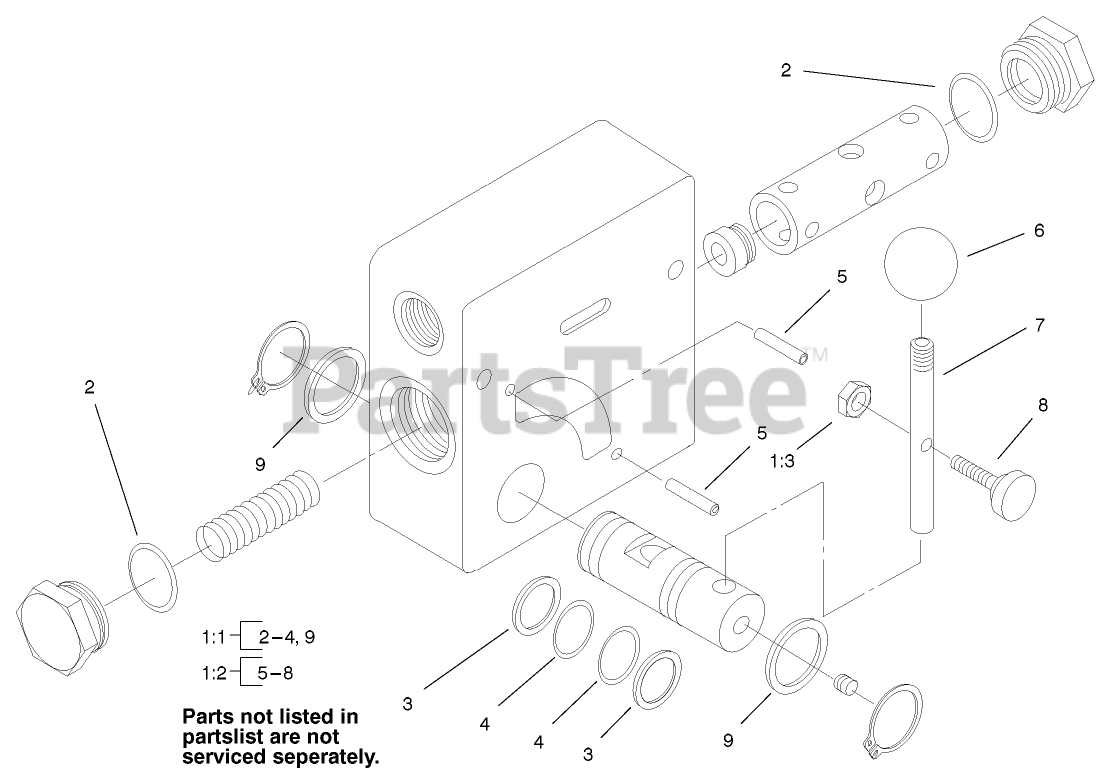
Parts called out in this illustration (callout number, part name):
1	VALVE-FLOW, HYDRAULIC
1:1	SEAL KIT
1:2	HANDLE HARDWARE KIT
1:3	NUT-LOCK, NI
